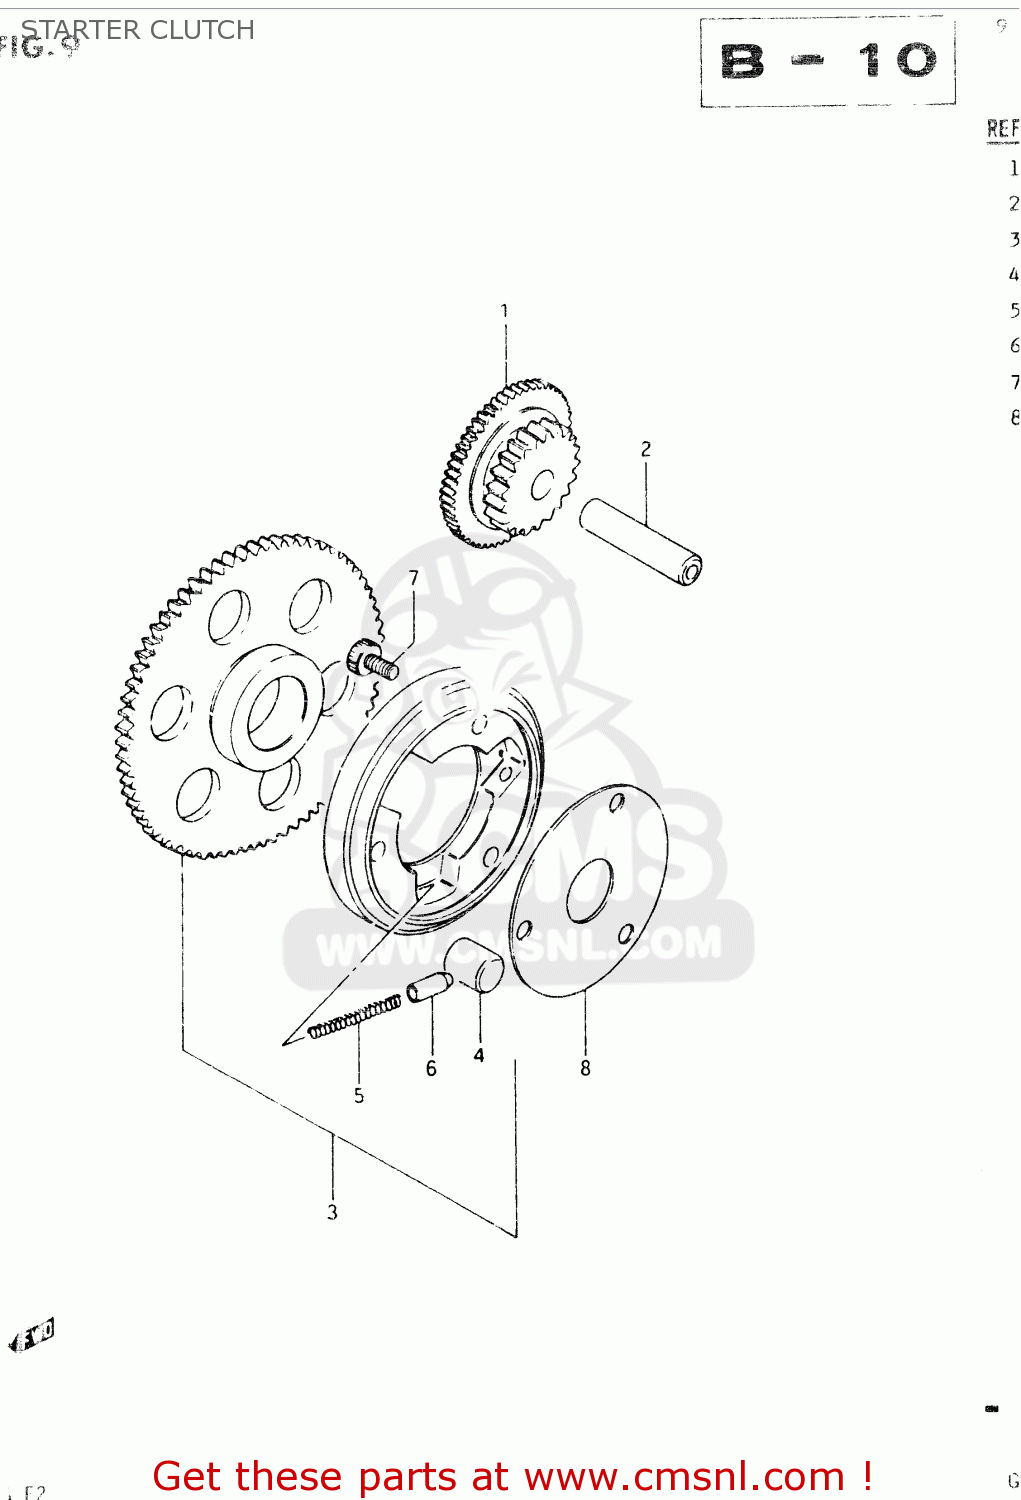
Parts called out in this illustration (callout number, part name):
1	GEAR,STARTER IDLE
2	PIN(7.4X13X56)
3	CLUTCH SET,STARTER
4	ROLLER(15X13)
5	SPRING
6	PIECE,PUSH
7	BOLT
8	SHIM,STARTER CLUTCH HUB
